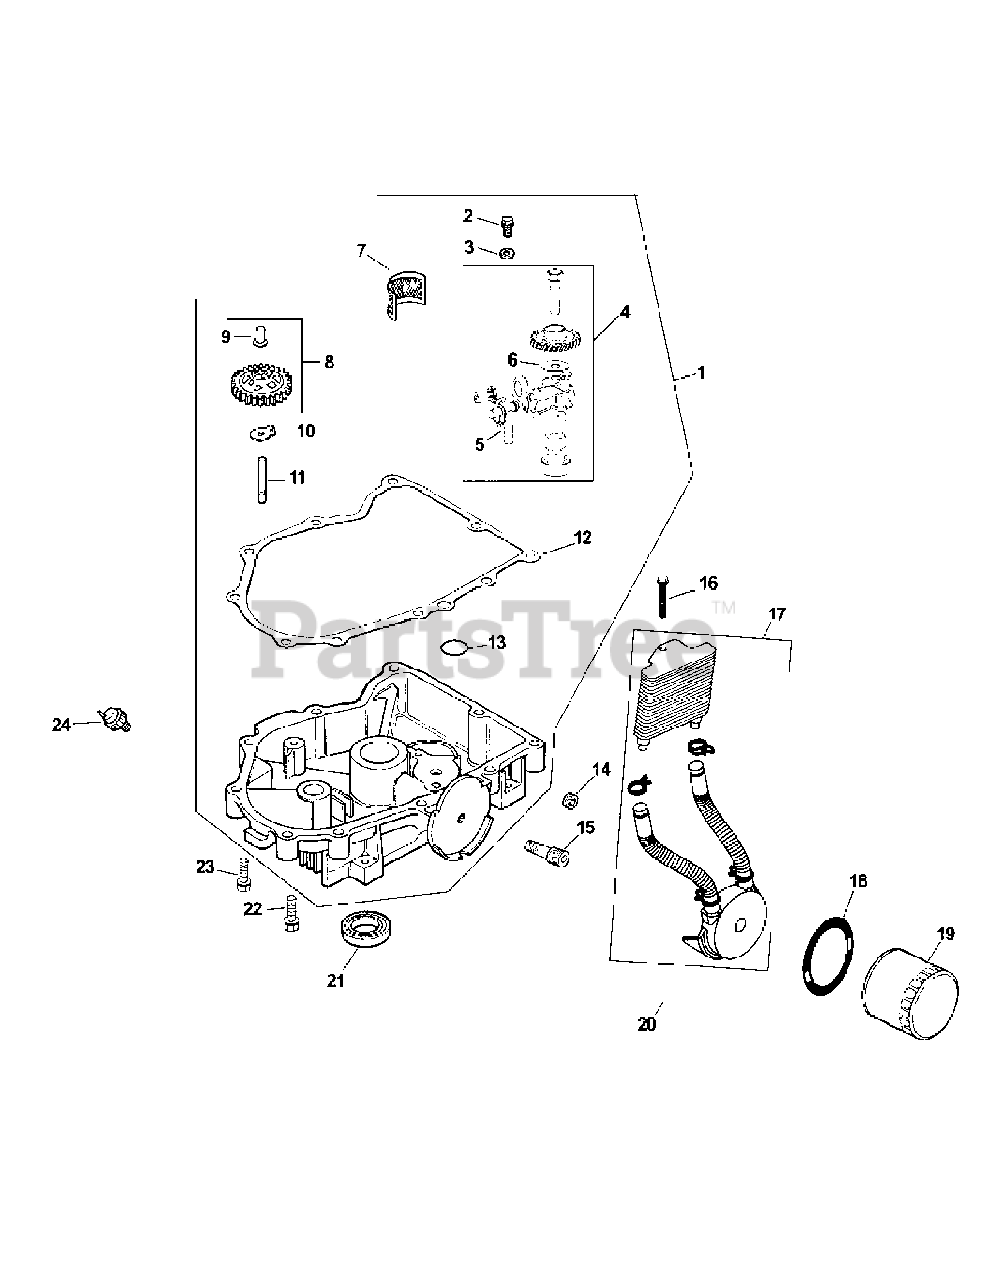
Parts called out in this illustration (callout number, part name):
1	Oil Pan w/Gasket Kit
2	Hex Flange Screw (M6 x 1.0 x 25)
3	Plain Washer 6mm
4	Oil Pump Assembly
5	Oil Pickup Tube
8	Governor Gear Kit
9	Governor Regulating Pin
11	Governor Gear Shaft
12	Oil Pan Gasket
14	Hex Plug 3/8"
15	Oil Filter Nipple
16	Hex Cap Screw (M6 x 1.7 x 18)
21	Oil Seal (PTO End)
22	Hex Flange Screw (M8 x 1.25 x 45)
23	Hex Flange Screw (M8 x 1.25 x 45)
24	Oil Pressure Switch
